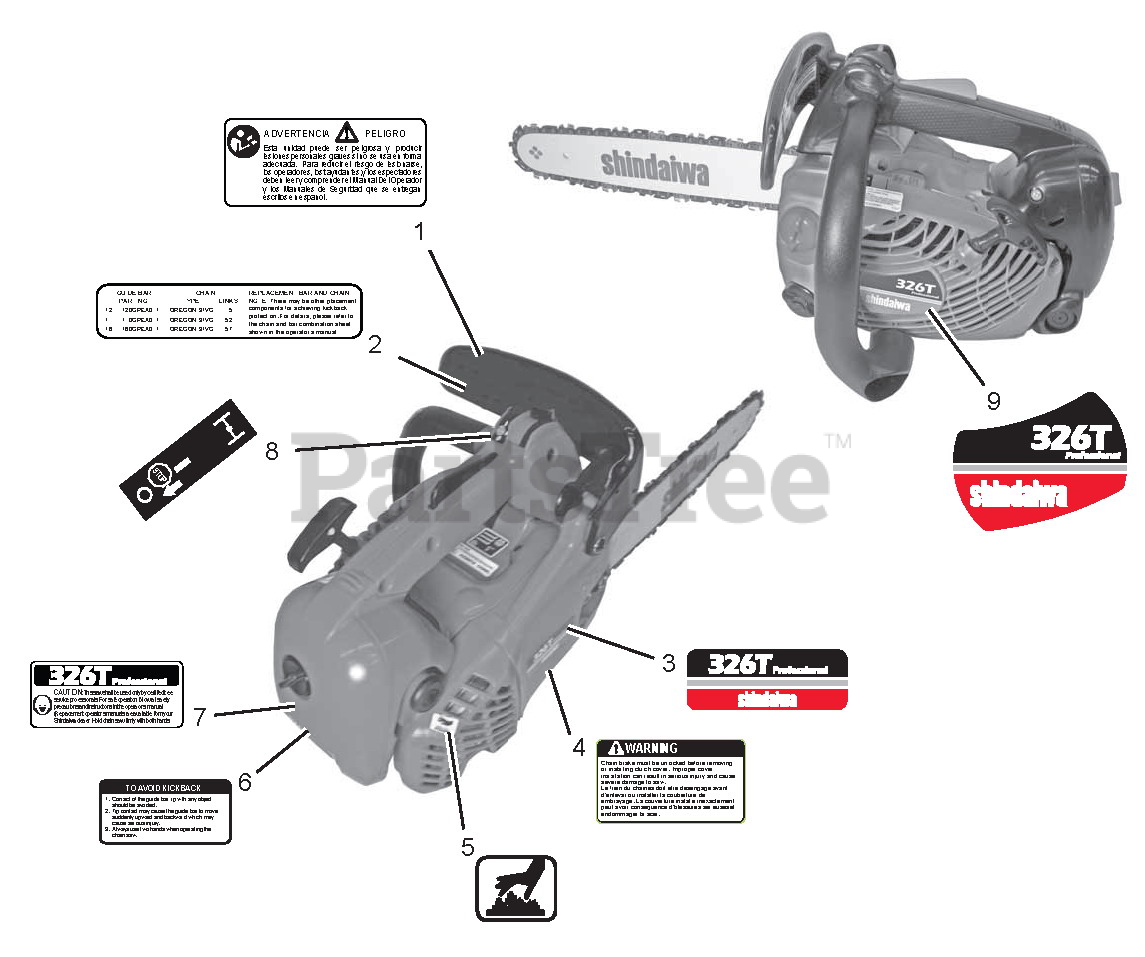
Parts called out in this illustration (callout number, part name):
1	LABEL - CAUTION -- SPANISH
2	LABEL - BAR & CHAIN
3	LABEL - MODEL 326T
4	LABEL - WARNING
5	LABEL - HOT SURFACE
6	LABEL - KICK BACK
7	LABEL - WARNING
8	LABEL - STOP
9	LABEL - MODEL 326T
